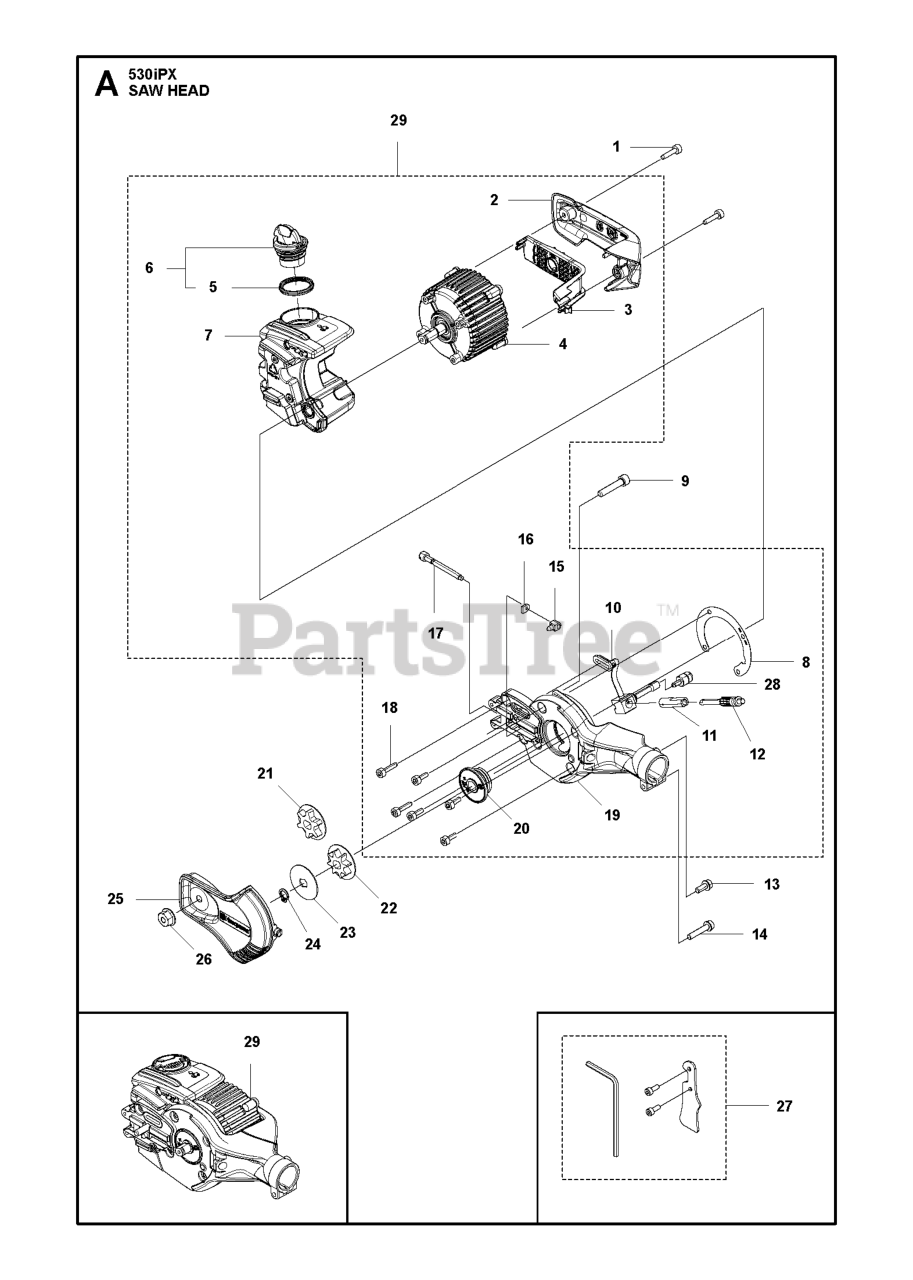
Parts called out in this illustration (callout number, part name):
1	SCREW
2	COVER MOTOR
3	BRACKET CABLE
4	MOTOR ASSY BLDC
5	GASKET TANK CAP
6	TANK CAP ASSY
7	OIL TANK ASSY
8	INSULATOR HEAT
9	SCREW IHSCM
11	PUMP CYLINDER
12	PISTON PUMP
17	SCREW CHAIN TENSIONER L 49
19	CHASSIS ASSY
20	PUMP PINION ASSY
21	SPUR SPROCKET
22	SPUR SPROCKET 1/4" 8T
24	RETAINING RING SGA 10
25	COVER CHAIN ASSY HUSQVARNA
26	HEXAGON NUT FLANGED
27	ACCESSORY BAG HOOK
28	OIL PLUMMET
29	CUTTING SYSTEM SPARE PART KIT
